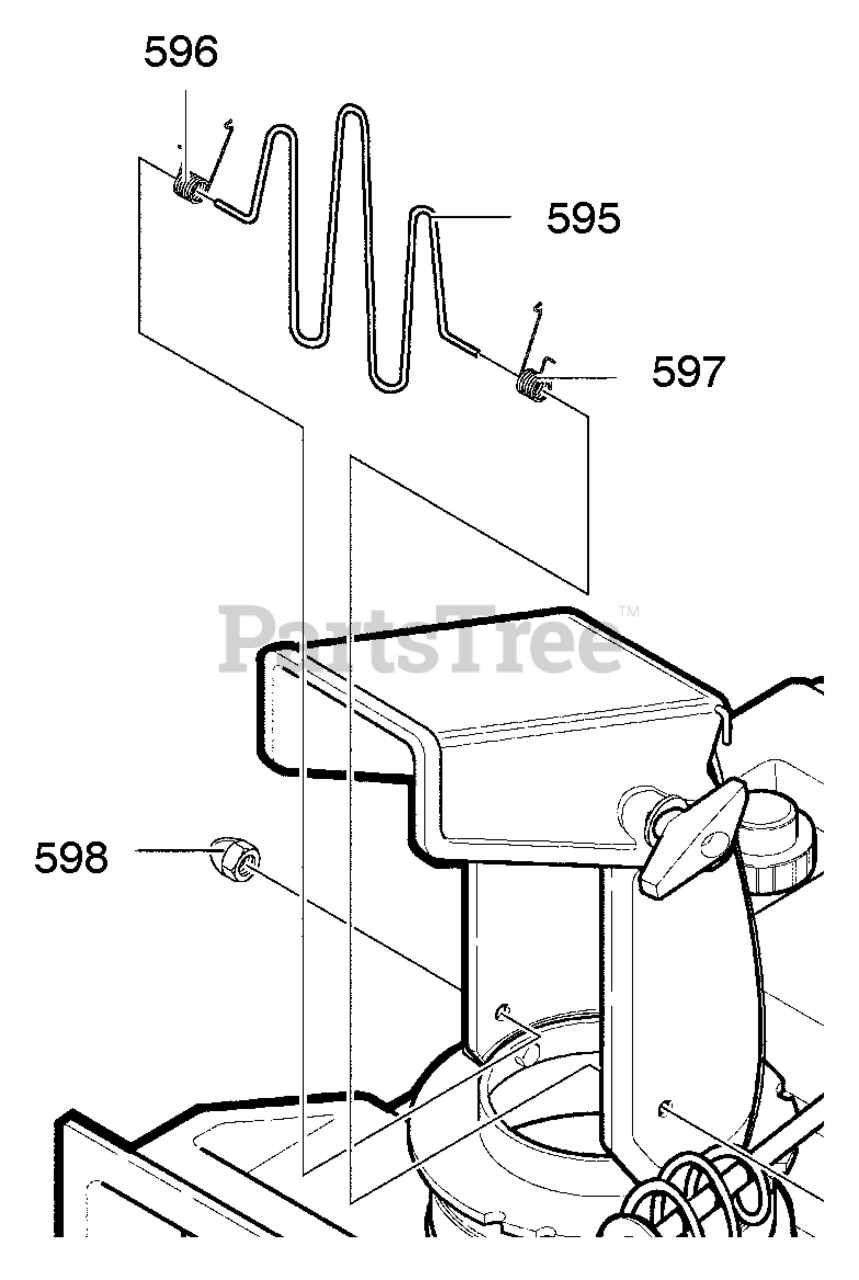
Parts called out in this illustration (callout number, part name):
595	GUARD, WIRE CHUTE
596	SPRING, TORSION
597	SPRING, TORSION
598	NUT, ACORN
